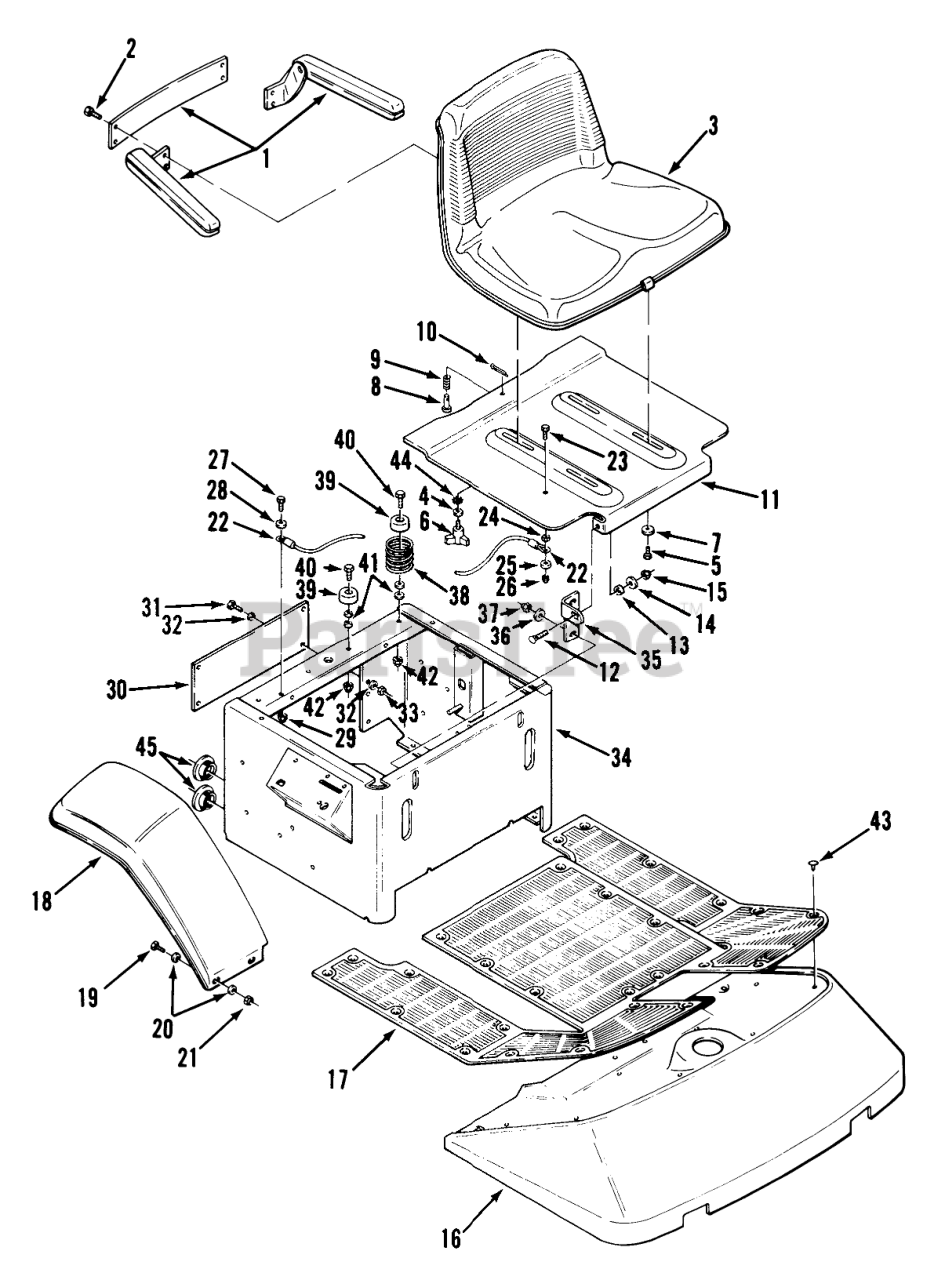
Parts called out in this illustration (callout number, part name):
1	KIT-ARMREST
2	Bolt
3	Seat
4	WASHER 5/16 SAE
5	BOLT 5/16-18X5/8
7	WSHR .312X1.0X11 GA
9	SPRING-COMPRESSION
10	Cotter Pin
11	PLATE SEAT PIVOT R
12	Bolt
13	SPACER
14	Washer
15	NUT
16	Floor Pan
17	Black Mat
18	Fender RH
18	Fender LH
19	Bolt
21	Nut
22	Cable
23	Bolt
24	Nut
25	Collar
26	Nut
27	Bolt
28	Collar
29	Nut
30	COVER-SEAT BOX R
31	Bolt
32	WASHER 5/16 SAE
33	Nut
34	Seat Support
35	Seat Pivot Bracket RH
35	Seat Pivot Bracket LH
36	Washer
37	NUT
38	SPRING-SEAT NYLON
39	BUMPER
40	Bolt
41	Collar
42	Nut
43	RIVET .25 PLASTIC
44	Washer-Lock
45	BUSHING-NYLON 1.500
